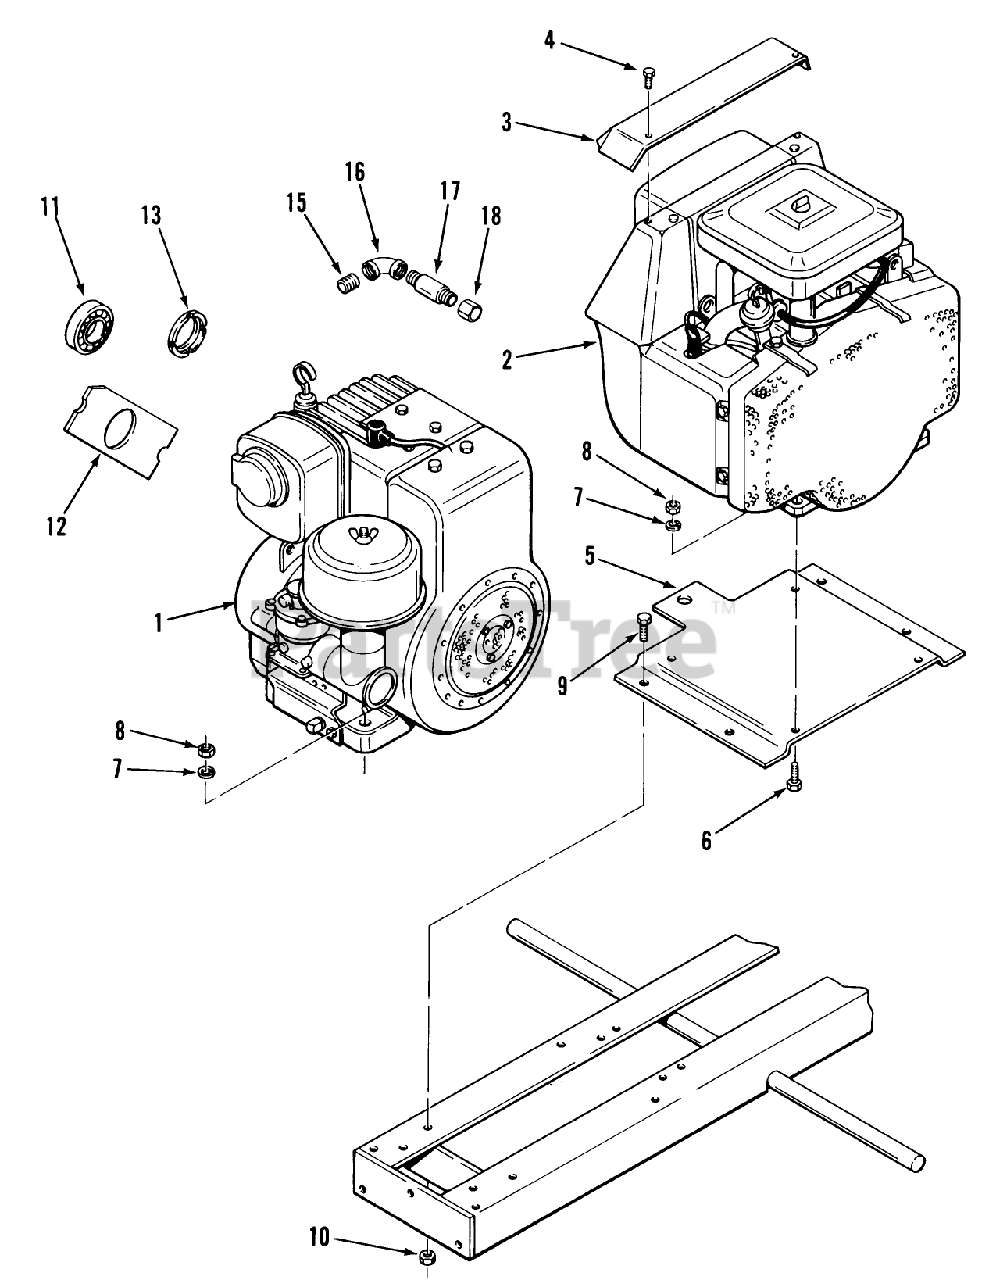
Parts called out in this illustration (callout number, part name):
1	Engine-11HP-BS Model 252417, Type 0664-01
2	Engine-18HP-BS Model 422437, Type 0663-01 GT-1800
2	Engine-16HP-BS Model 402417, Type 0665-01 GT-1642
4	Bolt
13	THRUST WASHER
